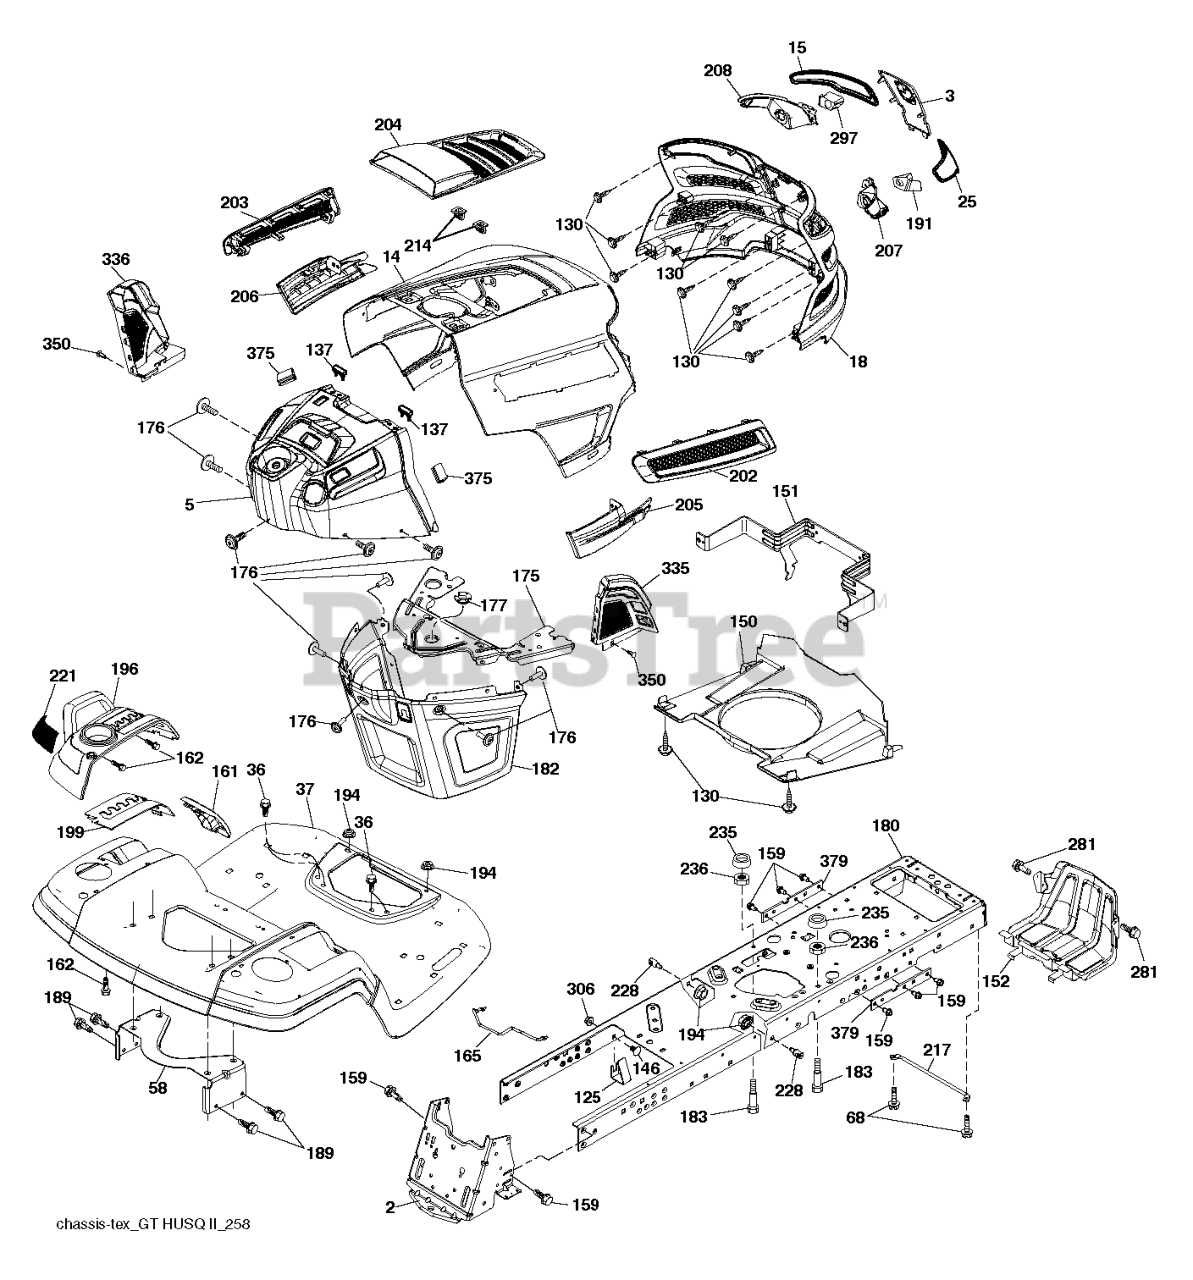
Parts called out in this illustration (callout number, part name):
2	DRAWBAR.STGT
3	APPLIQUE.SUBASM.GT.HUSQ.II
5	DASH.UPR.GT2.SRV.MIND.PTO
14	HOOD.ASM.HUSQVARNA.GT.TEX.ORAN
15	LENS.HEADLIGHT.LH.GTII.2011
18	GRILLE SUBASM.GT.II.LOW.HDLGHT
25	LENS.HEADLIGHT.RH.GTII.2011
36	SCREW 5/16"
37	FENDER.PNT.TX.GT.CH/FW/DL.HUSQ
58	BRKT.SUPPORT.FNDR/TANK
68	SCR 5/16-18 X 1/2 SELFTAP ZN
125	CLIP.FUEL.LINE
130	SCREW.#10 X 0.750.BOS
137	BUMPER DASH
146	BOLT.RDHD.SHT.SQNK.3/8-16X5/8
150	AIR.DUCT.GTV.BLACK
151	BRACKET.PIVOT.HOOD.GT.HUSQ.II
152	SHIELD.BROWNING.PNT.GT.V2
159	SCREW, 3/8-16X3/4
161	CONSOLE.WINDOW.FUEL.HUSQ.GT
162	SCREW.HI-LO.CONSOLE
165	SUPPORT.TANK.REAR.B/TE
175	PLATE.PNT.CROSSMEMBER.HUSQ/PRE
176	SCREW.#10-24X5/8.RN.QU
177	BUSHING STEERING
180	CHASSIS.LT/GT.BOLTED
182	DASH LOWER.HUSQ.PRED NO CRUISE
183	BOLT.5/16-18X1-1/4 FULL THD
189	SCREW
191	INSERT.REFLECTIVE.RH.HUSQ.GTII
194	NUT LOCK HEX FLANGE 5/16-18
196	SUBASM.CONSOLE.HUSQ.GT.DECKLFT
199	PLATE.DECK.LIFT.HUSQVARNA.GT
202	VENT.SIDE.RH.GT.HUSQ.II.
203	VENT.SIDE.LH.GT.HUSQ.II.498
204	VENT.TOP.HUSQ.GT2
205	SIDE.TRIM.RH.GT.HUSQ.II
206	SIDE.TRIM.LH.GT.HUSQ.II.GRAY
207	HEADLIGHT.CUP.BEZEL.HUS.GT2.RH
208	HEADLIGHT.CUP.BEZEL.HUS.GT2.LH
214	CLIP.RETAINER.TINNER.
217	ROD.PIVOT.HOOD
221	REFLECTOR.LH.TEX GT HU
228	STUD.FASTNER.W/ANTI-ROTATE
235	SPACER FENDER
236	NUT.CENTERLOCK.5/16-
281	SCREW 3/8-16X1
297	INSERT.REFLECTIVE.LH.HUSQ.GTII
306	NUT LOCK FLG 3/8-16 UNC
335	COVER.LOWER.DASH.RH.BLACK
336	COVER-LH.LOWER.DASH.GT2.BLACK
350	CLIP.X-MAS.TREE
375	BUMPER CLIP-ON. DASH 1"
379	CHASSIS.PLATE.REINFORCEMNT.431
